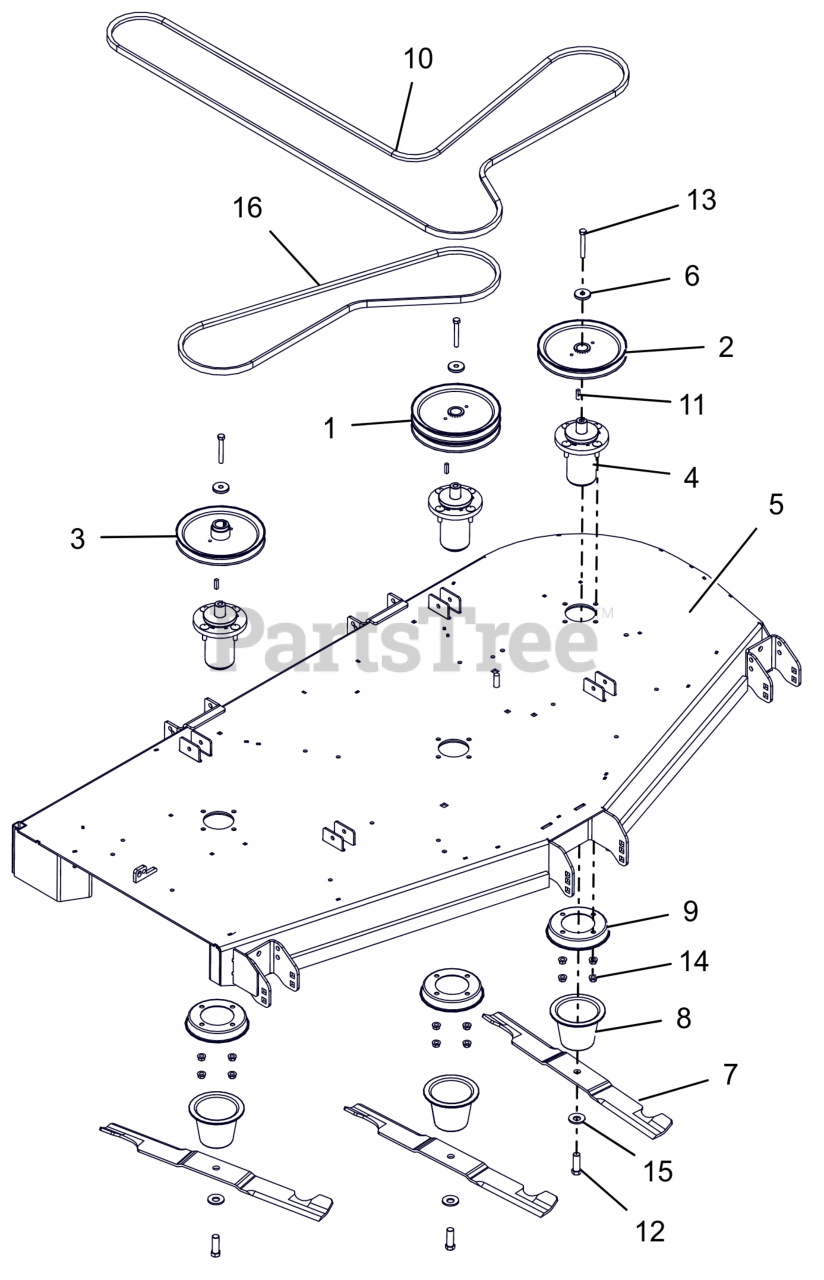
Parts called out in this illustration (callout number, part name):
1	SHEAVE-DOUBLE 1.00"IDX8.25"OD
2	SHEAVE-SINGLE 1.00"IDX8.25"OD
3	SHV-SINGLE 1.00"ID X 8.25"OD
4	ASM, MAINT FREE ALUM SPINDLE
5	WLDMT, 72" SIDE DISCHARGE DECK
6	RETAINER, SHEAVE
7	BLADE, 72"
8	GUARD, SPINDLE LOWER
9	GUARD, SPINDLE TOP
10	V-BELT, HB WRAPPED
11	KEY, SQ .25X.25X1.00 RC 40-50
12	BLT, HEX .62-18X1.75 G8 ZCC
13	BLT, HEX .38-16X2.75 G8 ZCC
14	NUT-LK-CTR-FLG .375-16 GF ZCC
15	WSHR-BLVL .669X1.535X.138
16	V-BELT, B-COGGED
